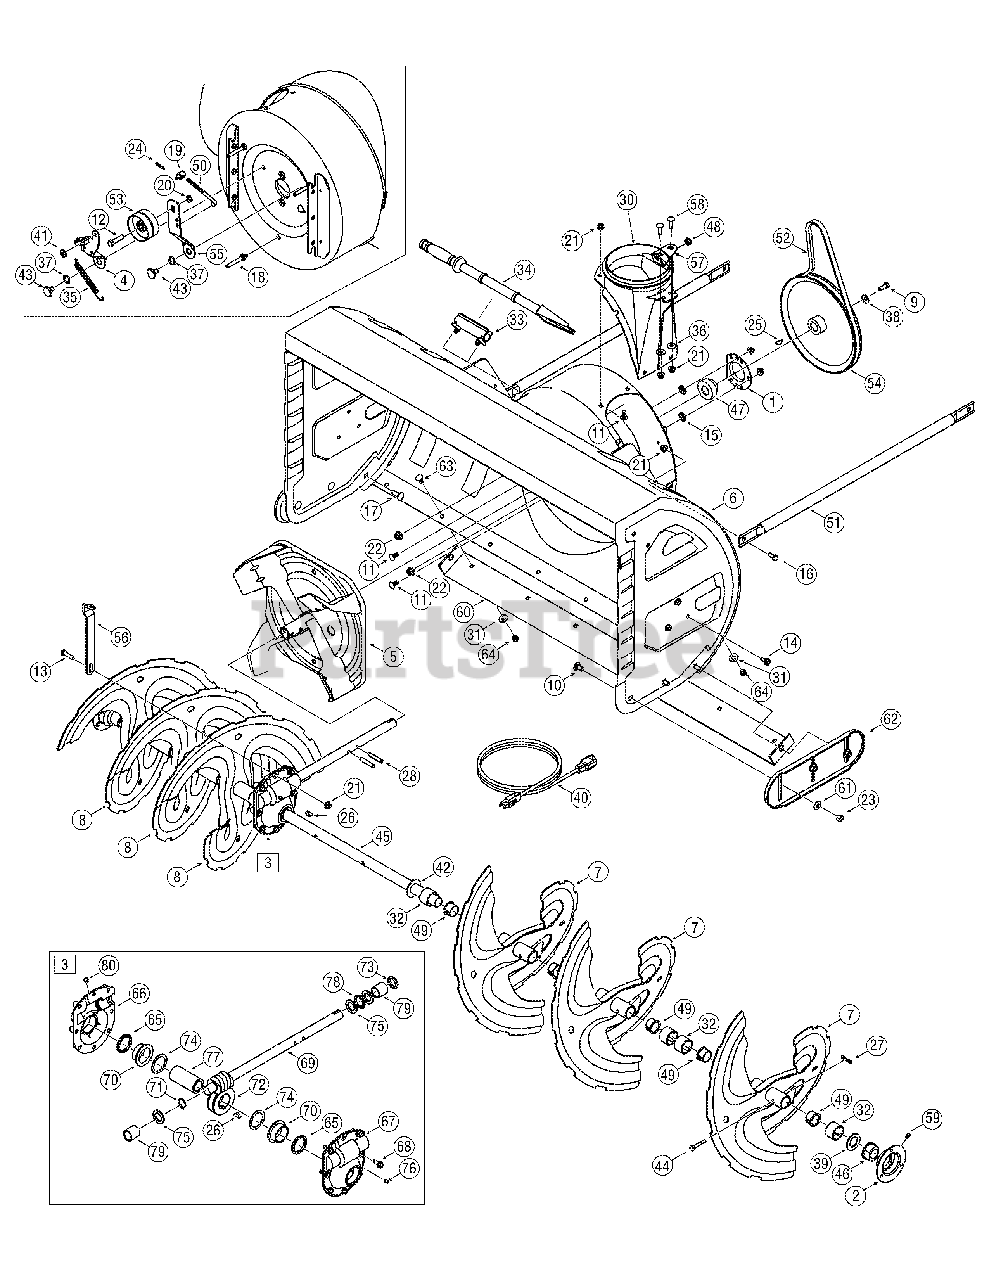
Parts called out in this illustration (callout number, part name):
1	Housing, Bearing
3	Gear Box Assembly, Auger
4	Bracket Ass’y, Auger Brake
9	Screw, Hex Cap Lock
10	Screw, Carr, Stnls Stl
11	Screw, Carr, 5/16-18 x .75
12	Scr, Hex Cap, 3/8-24 x 1.5
13	Scr,Hex Cap, 5/16-18 x 1.25
14	Screw, 5/16-18 x .750
16	Screw, 5/16-18 x .75 GR5
17	Screw, Carr,3/8-16 x 1.0
18	Scr., 5/16-18 x .4300
19	Ferrule
20	Nut, Hex Lock, 3/8-24
21	Nut, Flnge Lk, 5/16-18
22	Nut, Flg Lk, 3/8-16
23	Nut, Hex, Stnls Stl, 3/8-16
24	Pin, Internal Cotter
25	Key, Hi Pro, 3/16 x 3/4
26	Key, Woodruff, 1/4 x 3/4
27	Pin, Bowtie Cotter
28	Pin, Spirol, 5/16 x 1.75
30	Adapter, Chute, 6"
31	Washer, Bell, .34x.87x.06
32	Spacer, 1.0 x 1.5 x 1.0Lg
33	Clip, Mounting
34	Tool, Cleanout
35	Spring, Extension
36	Wash, Fl, .349 x .879 x .063
37	Wash,, .625 x .885 x .015
38	Washer, .34 x .872 x .06
39	Spacer, 1.004 x 1.375 x .25
40	Extension Cord, 110V
41	Washer, .344 x .75 x .12
42	Washer, 1.01 x 1.86 x .06
43	Screw, Shoulder, .625 x .17
44	Pin, Shear, .25 x 1.75
45	Shaft, Spiral, 45"
46	Bearing, Flange w/Flats
47	Bearing, Self Aligning
48	Bushing, Nylon
49	Bushing, Flange,
50	Rod, Auger Idler
53	Pulley, Flat Idler, 2.75 OD
54	Pulley, Auger Drive, 10.0
55	Bracket, Auger Idler
58	Scr., Carr., 5/16-18 x 1.00
59	Ftg., 3/16
60	Plate, Shave, 45"
61	Washer, Bell, .37x.87x.06
63	Screw, Carr., 5/16-18 x .75
64	Nut, Hex, Stnls Stl,
65	Oil Seal
66	Hsg, Ass’y, Auger, RH (Incl. Ref. #65 & 70)
67	Hsg, Ass’y, Auger, LH (Incl. Ref. #65 & 70)
68	Scr, LD, 5/16-18 x .750
69	Shf, Drive, Auger
70	Flange Bearing
71	Ext, Ret, Ring
72	Gear, Worm, LH
73	Seal, Oil
74	Wash, Flat, 1.52ID x 2.0 OD
75	Wash, Flat, .88 ID x .38 OD
76	3/16 Drive Lube Fitting
77	Shf, Gear, Worm
78	Brg, Thrust
79	Sleeve
